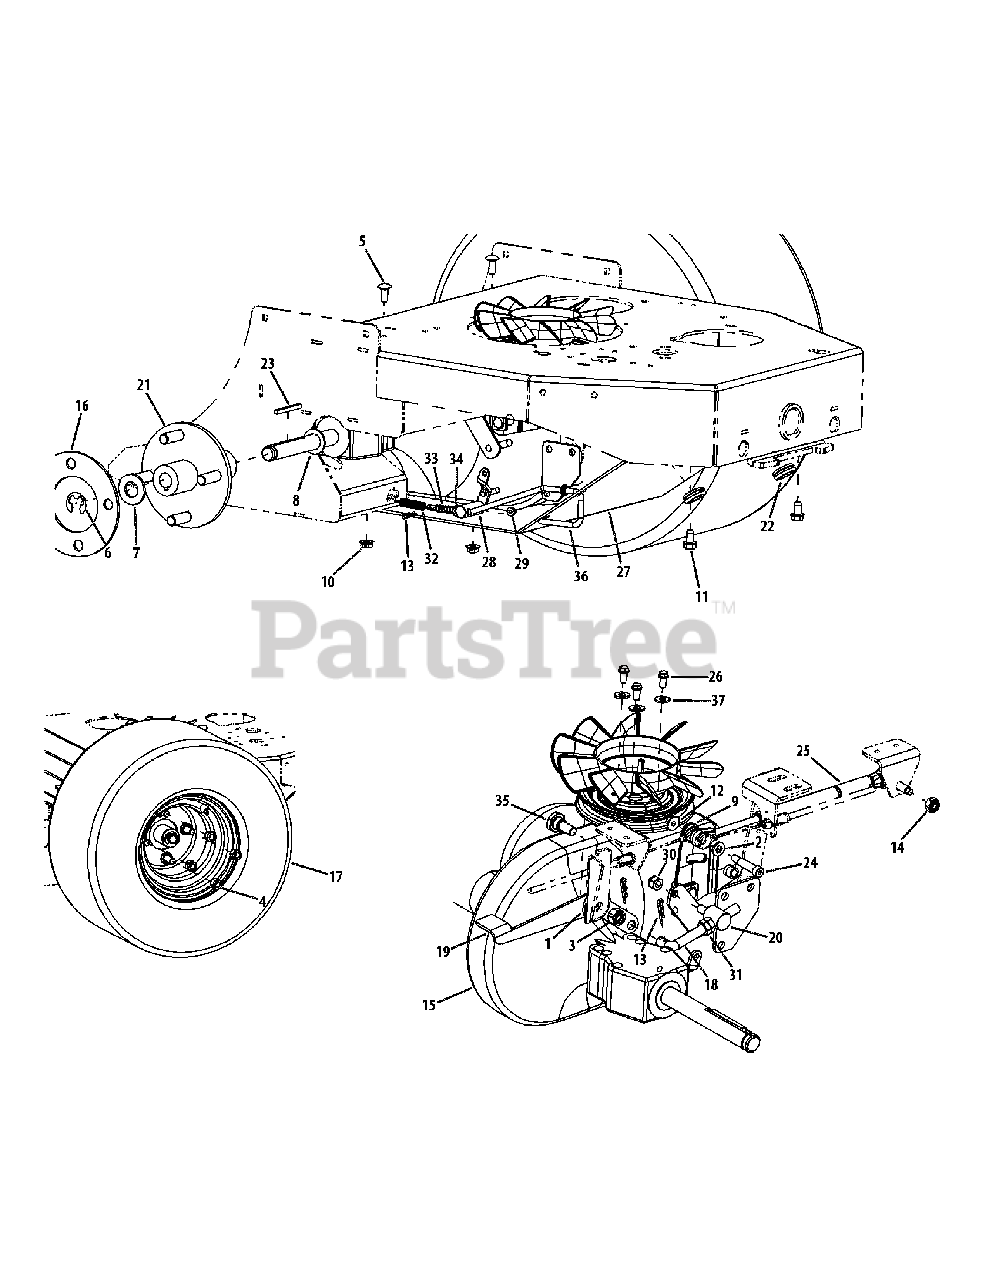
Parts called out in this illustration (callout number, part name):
1	Washer, 1/2
2	Washer, 5/16
3	Nut, 3/8-16
4	Lug Nut, 1/2-20
5	Carriage Bolt, 5/16-18 x .75
7	Washer, .781 ID x 2.00 OD x .105
8	Washer, .06 x .776 x 1.25, SS
9	Washer, 1/4 x .630 x .0515
10	Nut, 5/16-18, Hex Flange Lock
11	Self Tapping Screw, 5/16-18 x .625
12	Nut, 1/4-20
13	Cotter Pin, .072 x 1.12 Long
14	Nut, M8, Top Lock
15	Transmission, Hydro Gear
17	Wheel Assembly, 18 x 8.50-8
18	Brake Lever Rod
19	Brake Lever
20	Pivot Brake Joint
20	Ferrule, .750 x .313
21	Wheel Hub Assembly
22	Rubber Grommet
23	Key, 3/16 x 3/16 x 2
24	Shoulder Bolt, 5/16 x 1.00
25	Damper Assembly
26	Self Tapping Screw, 1/4-20 x .75
27	Transmission Skid Plate
28	Ferrule, .625 x .25
29	Nut, #10-24, Nylon Lock
30	Nut, 5/16-18, Nylock
31	Hex Jam Nut, 3/8-24
32	Spring, 0.38 x 0.035 x 2.00
33	Spring, 0.340 x 1.38 LG
34	Washer, .265 x .562 x .025
35	Shoulder Bolt, .500 x .270, 3/8-16
36	Bypass Rod
37	Lock, Washer
